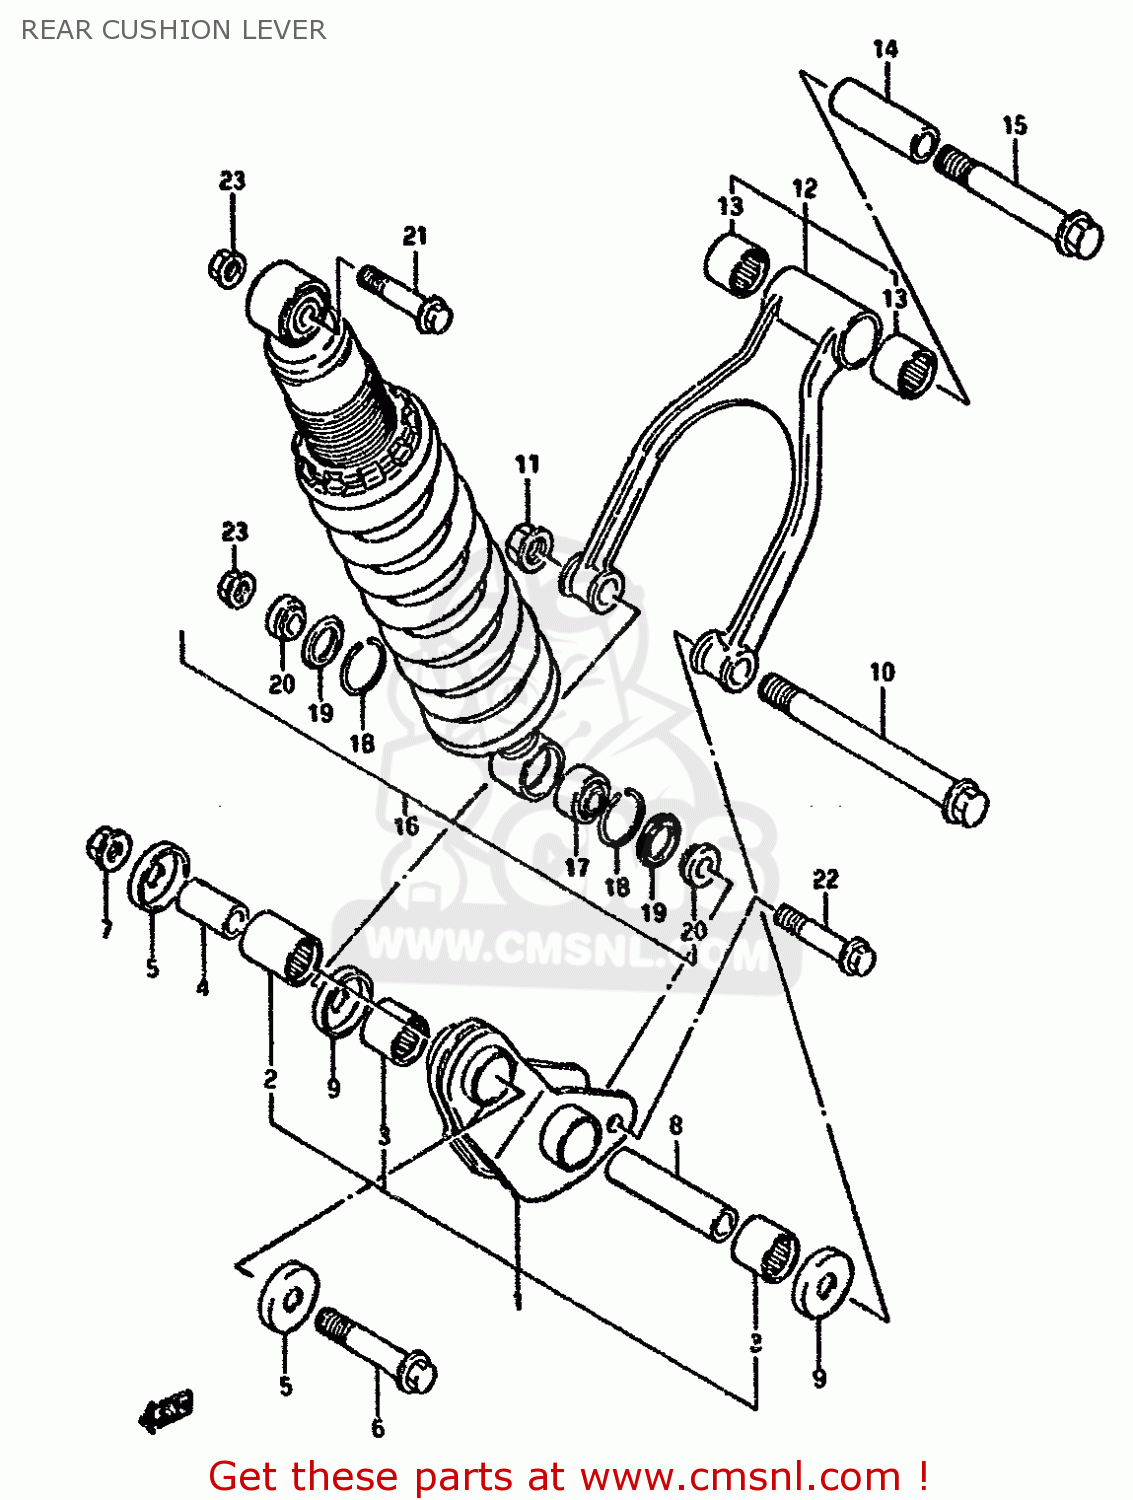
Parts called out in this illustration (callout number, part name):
1	LEVER SET, REAR CUSHION
2	BEARING(20X27X30)
3	BEARING(20X27X23.5)
4	SPACER,RR CUSHION LEVER FR
5	SEAL,RR CUSHION LEVER FR DUST
6	BOLT,RR CUSHION LEVER FR
7	NUT 12MM
8	SPACER (14X20X78)
9	SEAL,RR CUSHION LEVER CTR DUST
10	BOLT,RR CUSHION ROD LWR
11	NUT
12	ROD SET,REAR CUSHION,LEFT
13	BEARING(20X27X23.5)
14	SPACER (14X20X63)
15	BOLT,RR CUSHION ROD UPR
16	ABSORBER ASSY,RR SHOCK
17	BEARING,RR CUSHION LEVER
18	RING,STOPPER
19	SEAL,DUST RR SHOCK ABSORBER
20	COLLAR
21	BOLT(10X50)
22	BOLT(10X54)
23	NUT
